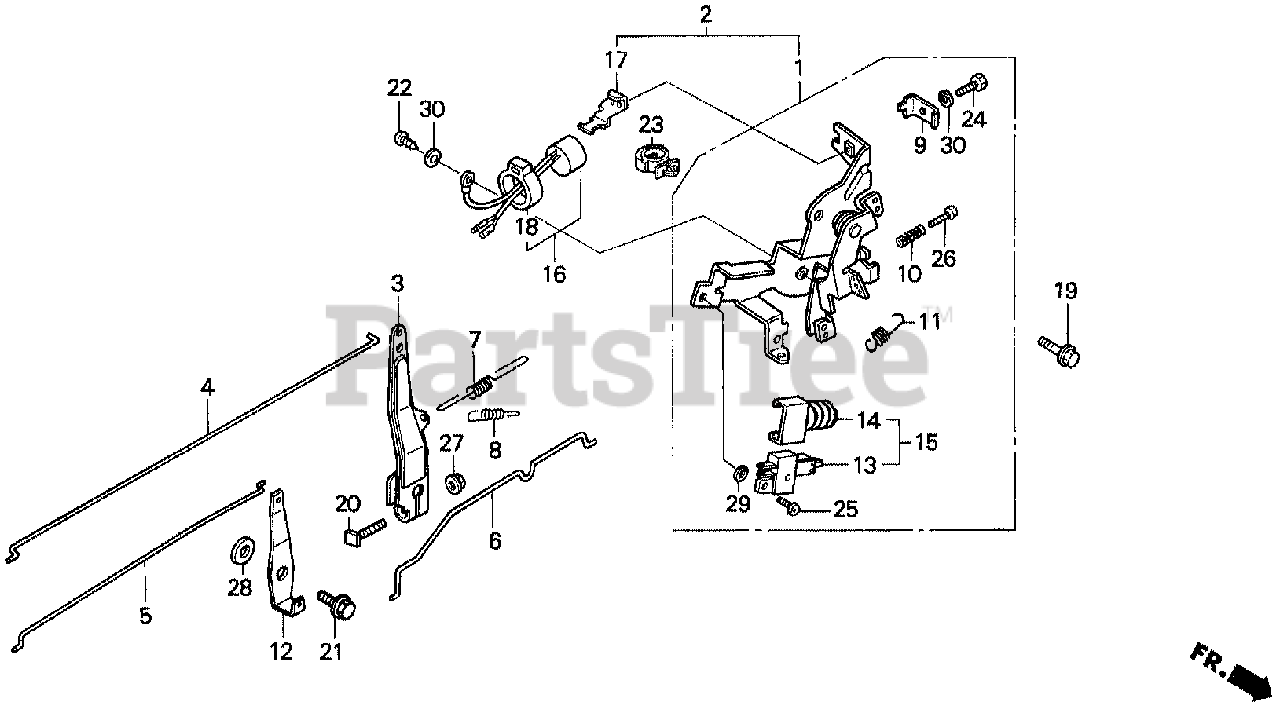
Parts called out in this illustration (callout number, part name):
1	CONTROL ASSY.
3	ARM, GOVERNOR
4	ROD, GOVERNOR
5	ROD, CHOKE
6	ROD, JOINT
7	SPRING, GOVERNOR
8	SPRING, GOVERNOR PRIMARY
9	HOLDER, CABLE
10	SPRING, CONTROL ADJUSTING
11	SPRING, CABLE RETURN
12	LEVER, CHOKE JOINT
13	SWITCH ASSY., ENGINE
14	COVER, SWITCH
15	SWITCH ASSY., ENGINE STOP
19	BOLT, FLANGE (6X12) (CT200)
20	BOLT, GOVERNOR ARM
21	BOLT, FLANGE (6MM)
24	BOLT, RECESSED (5X14)
24	BOLT, RECESSED (5X16)
25	SCREW, PAN (4X14)
26	SCREW, PAN (5X20)
27	NUT, FLANGE (6MM)
28	WASHER, PLAIN (6MM)
29	WASHER, SPRING (4MM)
30	WASHER, SPRING (5MM)
